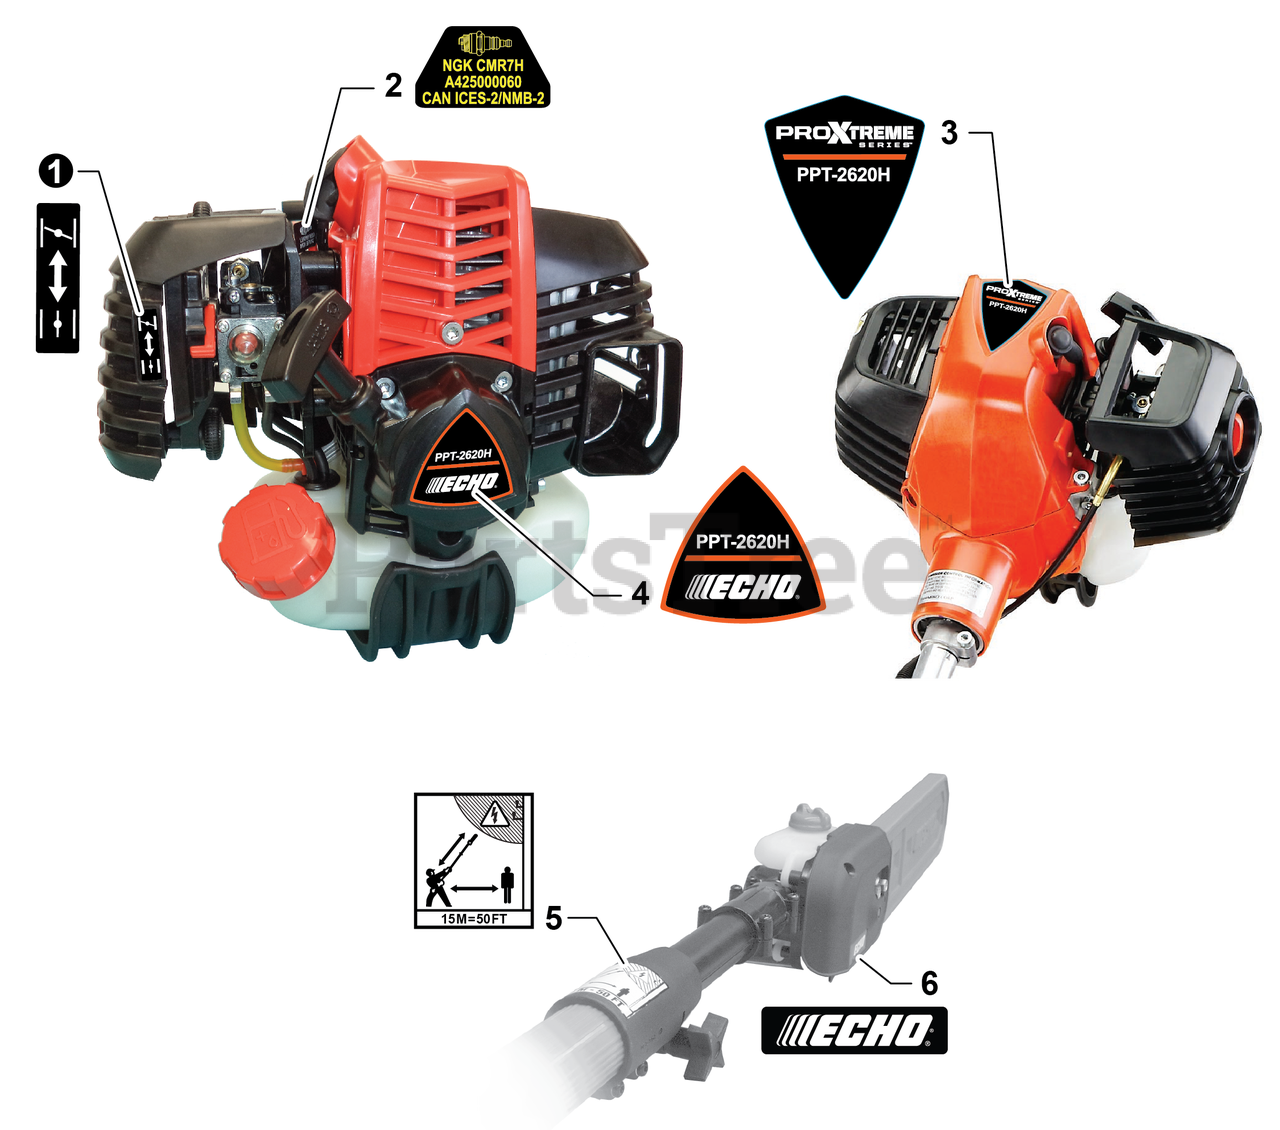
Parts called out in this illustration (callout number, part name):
1	LABEL, CHOKE
2	LABEL, SPARK PLUG - CMR7H
3	LABEL - MODEL PPT-2620H
4	LABEL, RECOIL STARTER - PPT-2620H
5	LABEL, CAUTION
6	LABEL, ECHO
